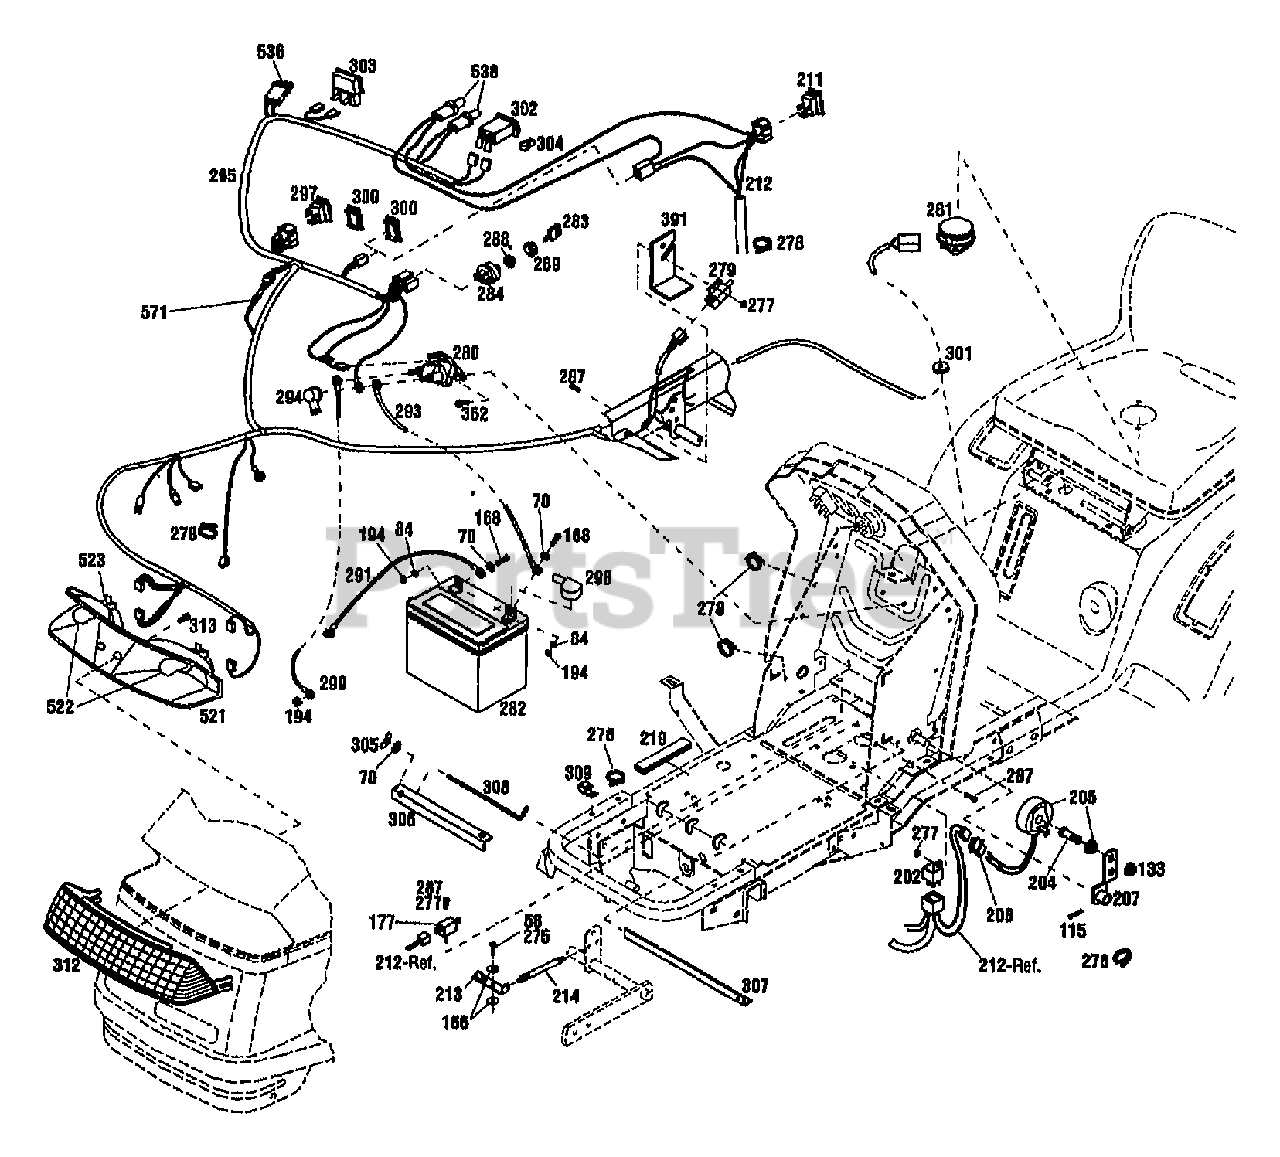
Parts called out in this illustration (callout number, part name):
58	NUT-HT LK 1/4-20 {13099}
70	WASHER-FLAT 1/4 SAE
84	WASHER-LK .25 ZP
115	PIN-ROLL .188X1.0 {13099}
133	NUT-WHIZ LOCK {13099}
166	WASHER-FLAT 1.25X.28X.062 ZP {13099}
168	SCR-HH 1/4-20X.75 G5 ZP
177	SWITCH {13099}
194	NUT-HEX 1/4-20 ZP
202	RELAY-SPEED CONTROL {13099}
204	SCR-SPECIAL {13099}
205	ASSM-MAGNET {13099}
206	PIN-TERM HOUSING {13099}
207	ARM-CRUISE {13099}
211	SWITCH-CRUISE {13099}
212	HARNESS-CRUISE {13099}
213	ARM-CRUISE {13099}
214	SPRING {13099}
275	SCR-HH 1/4-20X.625 G5 ZP
277	NUT W/LKWASHER 10-24 ZP
278	TIE-CABLE NYLON BLACK
279	SWITCH
280	SOLENOID
281	SWITCH-SEAT
282	BATTERY {13096/097}
282	BATTERY {13099}
283	KEY-IGNITION
284	SWITCH-IGNITION
287	SCR-HHS 10-24X.625 ZP
288	NUT-SWITCH
289	CAP-SWITCH
290	CABLE-STARTER
291	CABLE-BATTERY (-)
293	CABLE-BATTERY
294	BOOT-SOLENOID
295	HARNESS-WIRING {13096/097}
295	HARNESS-WIRING {13099}
297	SWITCH-PTO
298	BOOT-TERMINAL
300	COVER-SWITCH {13096/097}
301	GROMMET
302	METER-HOUR
303	AMMETER {13099}
304	CLIP-TINNERMAN {13099}
305	NUT-WING
306	CLAMP-BATTERY
307	BRKT-BATTERY LOWER
308	SCR-HOOK
309	CLIP-J
312	LENSE-HEADLIGHT
362	SCR 1/4-20X.5 FL SELF TAP
391	BRACKET-SWITCH
521	HEADLGT-REFL (PART OF 1772002)
522	LIGHTBULB
523	SOCKET
536	FUSE
538	LIGHTBULB
571	ASSM-DIODE
